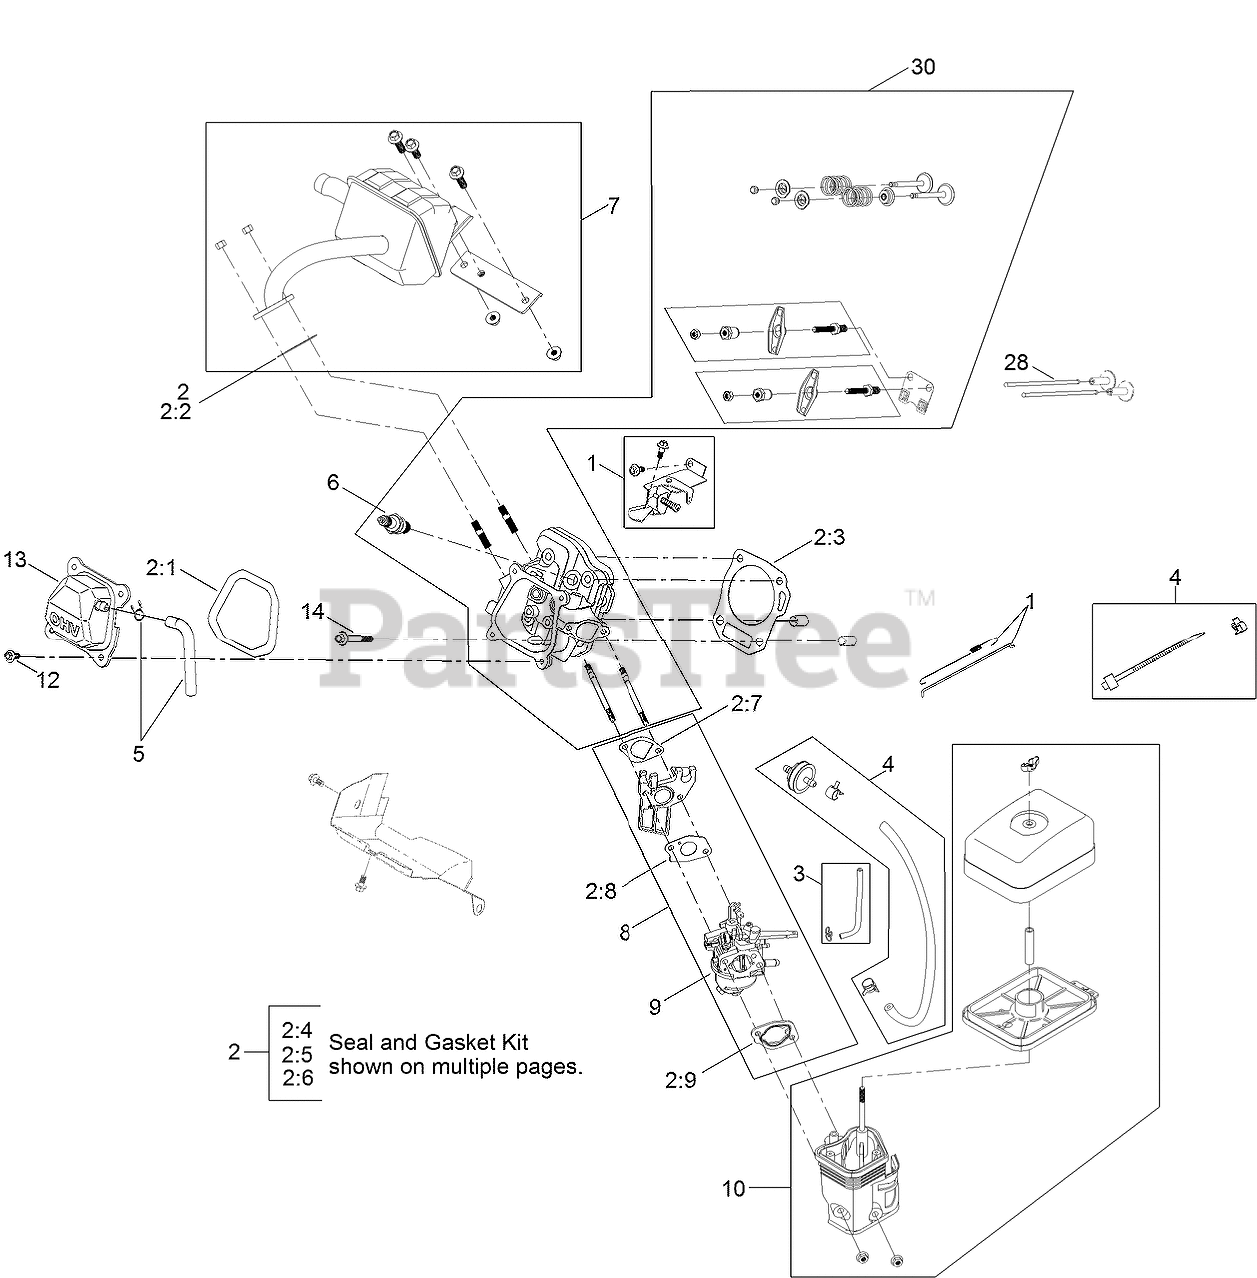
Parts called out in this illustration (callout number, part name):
1	GOVERNOR KIT
2	GASKET AND SEAL KIT
2:1	GASKET-COVER, VALVE
2:2	GASKET-EXHAUST
2:3	GASKET-HEAD, CYLINDER
2:5	SEAL-OIL
2:6	GASKET-COVER, CRANKCASE
2:7	GASKET-CARBURETOR
2:8	GASKET-CARBURETOR
2:9	GASKET-CARBURETOR
3	PRIMER LINE KIT
4	FUEL LINE KIT
5	BREATHER TUBE KIT
7	MUFFLER KIT
8	CARBURETOR KIT
9	CARB REPAIR KIT WITH GASKETS
10	HEATER BOX KIT
12	SCREW-HHF
13	VALVE COVER ASM
14	SCREW-HHF
28	ROD-PUSH
30	COMPLETE HEAD ASM
